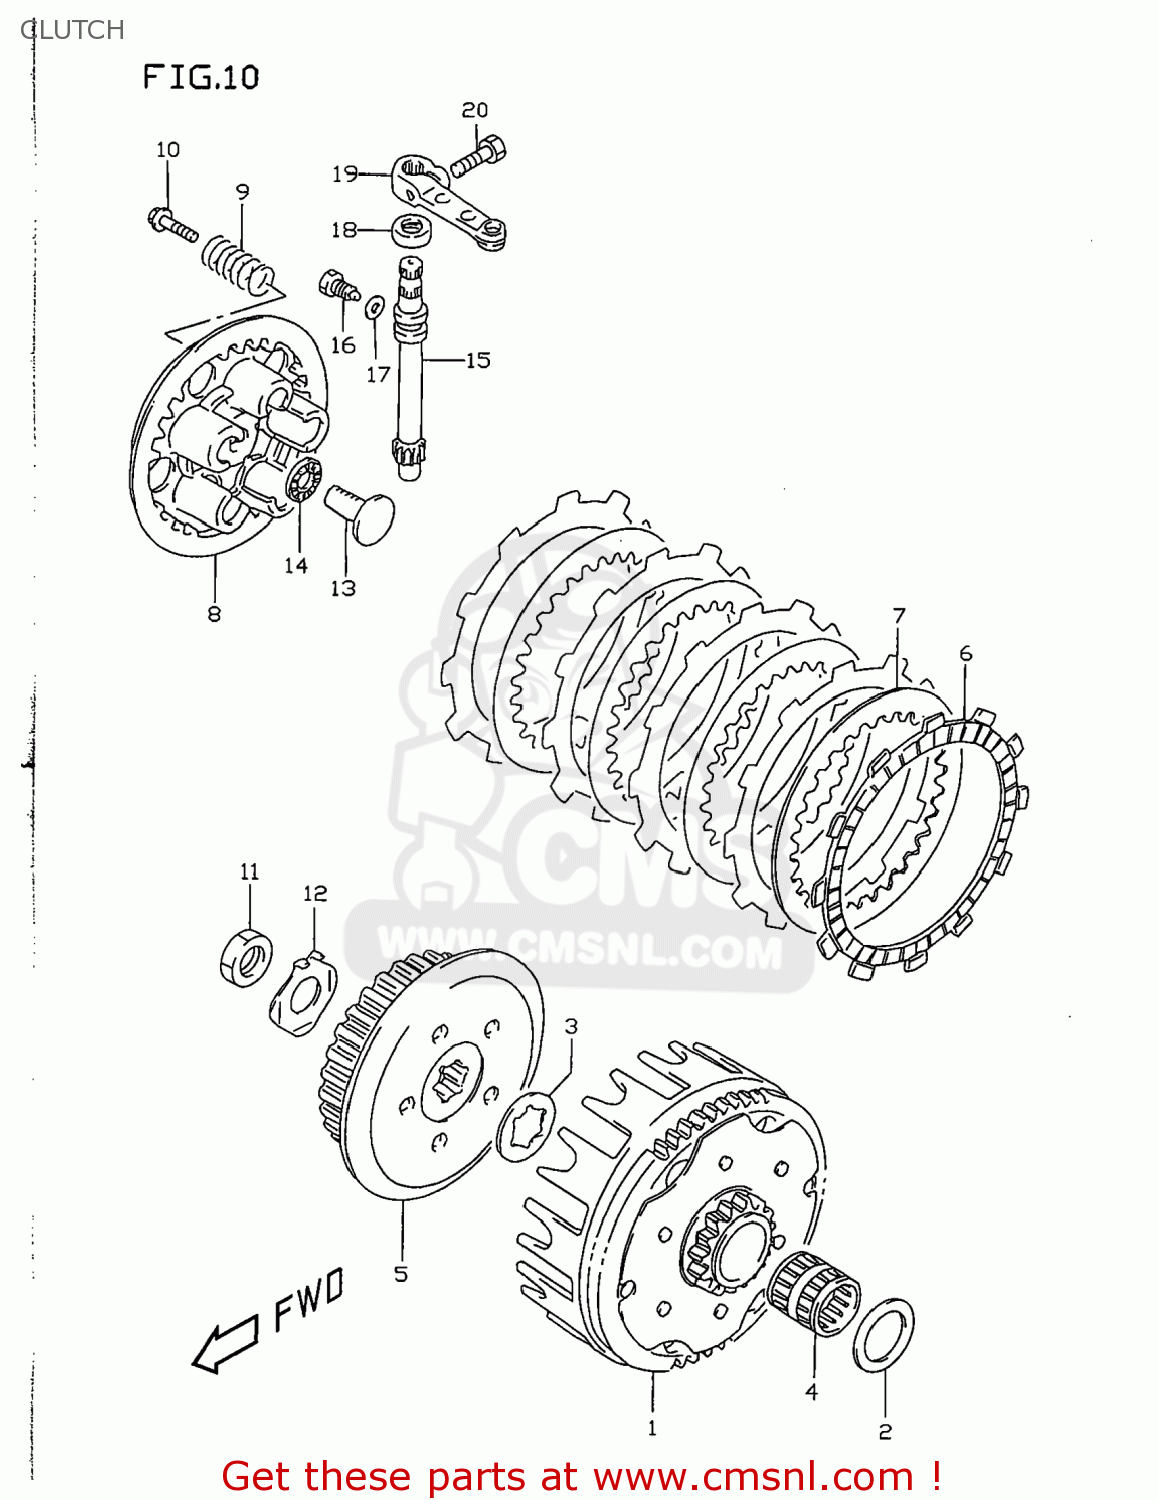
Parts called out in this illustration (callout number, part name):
1	GEAR ASSY,PRI DRIVEN(NT:62/16)
2	WASHER,THRUST
3	WASHER,LOCK
4	BEARING(20X25X26)
5	HUB COMP,CLUTCH SLEEVE
6	PLATE,CLUTCH DRIVE(T:3.0) (NAS)
7	PLATE,CLUTCH DRIVEN(T:2.0) (NAS)
8	DISC,CLUTCH PRESSURE
9	SPRING
10	BOLT 5X16
11	NUT
12	WASHER
13	RACK,CLUTCH RELEASE
14	BEARING(10X22X2.8)
15	PINION,CLUTCH RELEASE
16	BOLT
17	GASKET(6.2X11X1).2 (NAS)
18	SEAL,OIL(10X17X5)
19	ARM,CLUTCH RELEASE
20	BOLT
